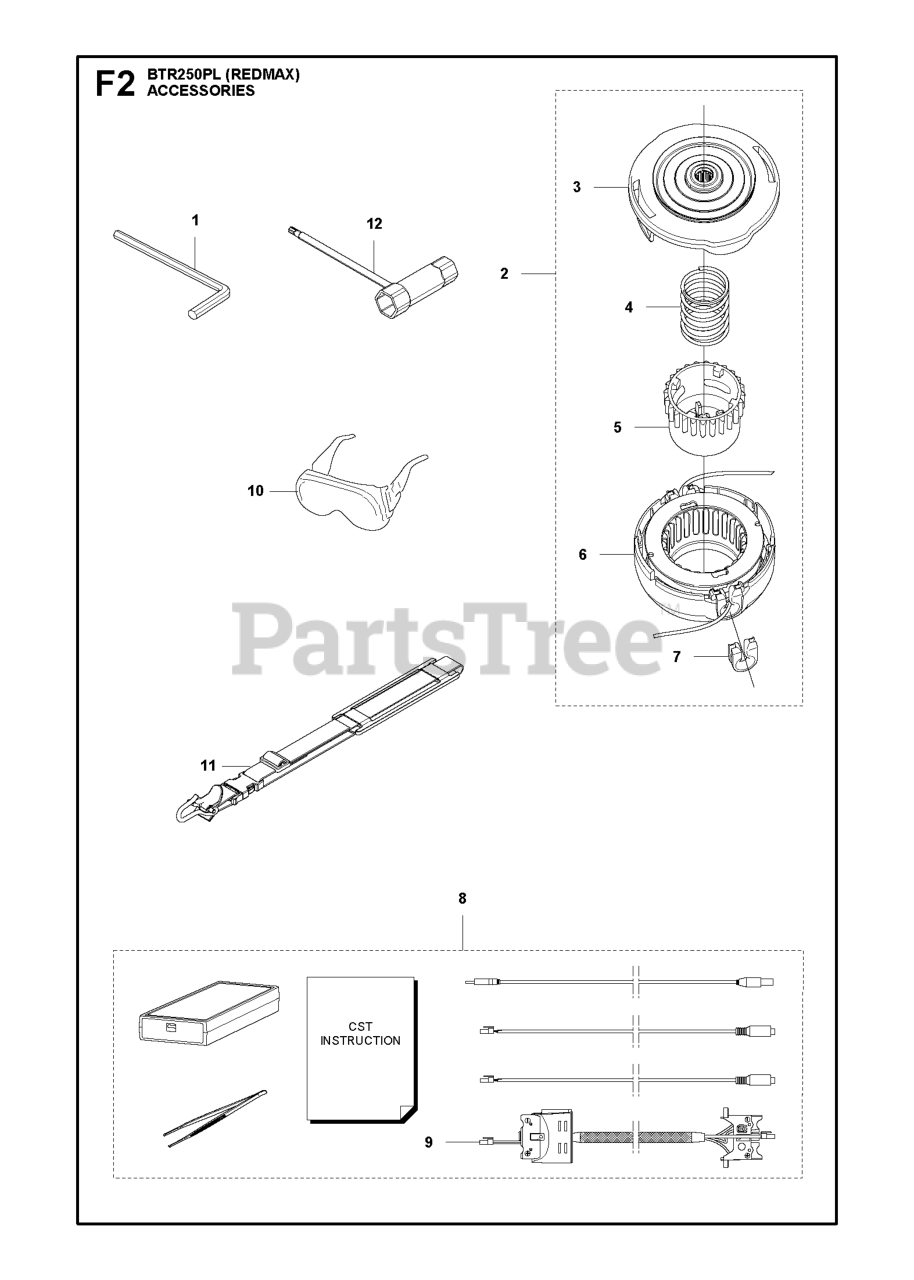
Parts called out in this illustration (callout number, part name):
1	L-SPANNER
2	RP_T25 TRIMMER HEAD 10MM(BATT
3	HOUSING ASSY
5	KNOB T25 B BLACK
8	DIAGNOSTIC TOOL KIT
9	WIRING ASSY
11	STRAP ASSY
12	COMBINATION WRENCH TORX
